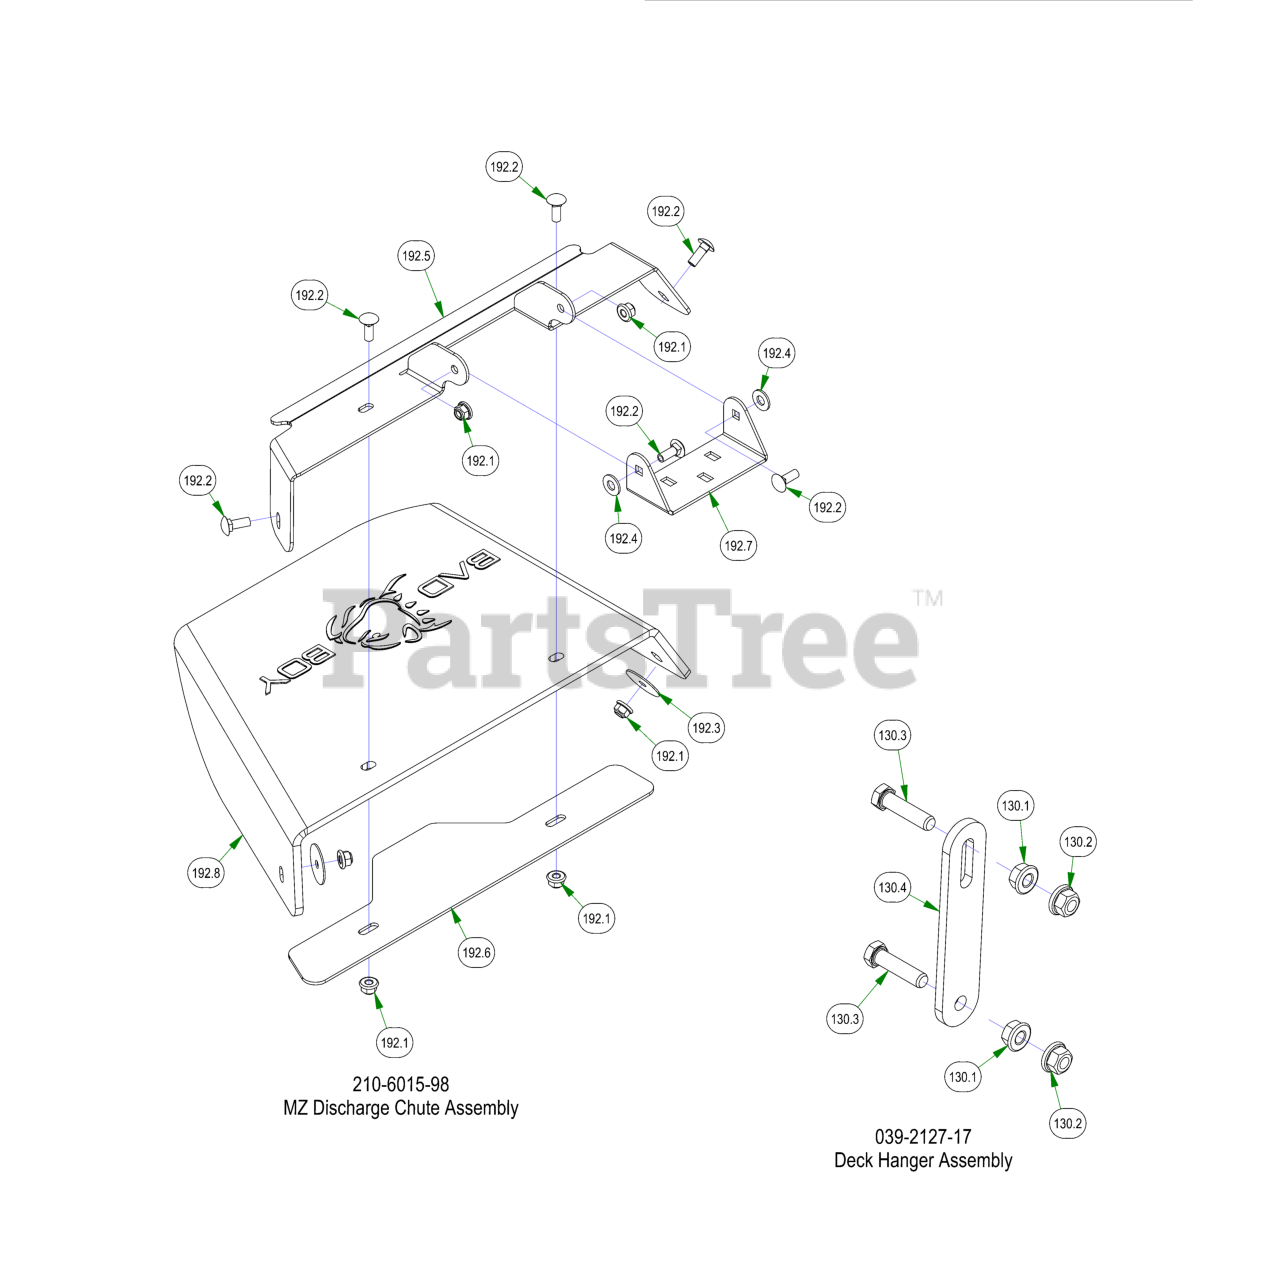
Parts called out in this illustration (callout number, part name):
130	Deck Hanger Assembly
130.1	3/8-16 HEX SERRATED FLANGE NUT HARD/ZINC
130.2	3/8-16 NYLON INSERT FLANGE LOCKNUT (GR.F) ZINC
130.3	3/8-16 X 1-1/2 HEX CAP SCREW (GR.5) ZINC
130.4	2017 MZ/ZT Deck Hanger
192	MZ Discharge Chute Assembly
192.1	5/16" Nylon Flange Nut
192.2	5/16" x 7/8" Carriage Bolt
192.3	5/16 Fender Washer
192.4	.360 ID Plastic Washer
192.5	Discharge Chute Bracket 48 MZ (Upper)
192.6	2017 MZ Discharge Chute Bracket-Lower
192.7	Chute Hanger 48 MZ
192.8	Rubber Discharge Chute MZ (Component)
